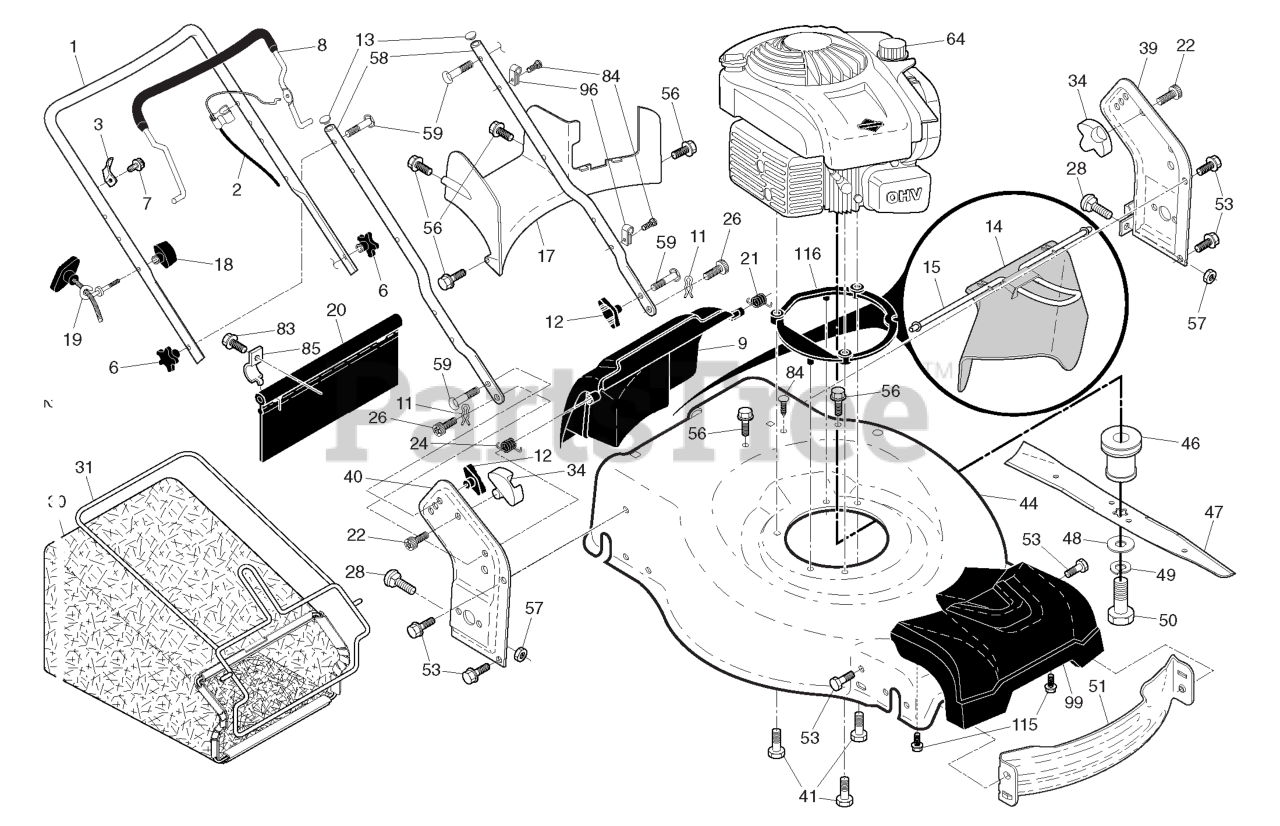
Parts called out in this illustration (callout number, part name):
1	HANDLE.UP.DST.SS/VS.FG/RG.NHGY
2	RP.CABLE.MZR.RGD.PLUS.STRT
3	BRACKET.UPSTOP.RT
6	KNOB.HANDLE.PLASTIC.STAR.BLACK
8	BAIL.ARM.ASSY:STRAIGHT OM
9	DOOR.REAR.ASM.22+GEN.FG/RG.498
11	COTTER.HAIRPIN.DOOR/HANDLE.PIV
12	KNOB, DEFLECTOR
13	PLUG.PLASTIC.7/8".14-20.GAUGE
14	DEFLECTOR.CHUTE.22+REAR
15	HANDLE DEFLECTOR.22+REAR
17	BAFFLE.REAR.22+RGD.AWD.PLASTIC
18	T-KNOB.NEW ROPE GUIDE
19	GUIDE.ROPE.BLK.ZINC.CHROM
20	SKIRT.REAR.22PLUS.RGD.LW(2 2MC
21	SPRING.LH.BLACK
22	SCREW.PAN.HEAD.#10
24	SPRING.RH.GRAY
26	SCREW,DOOR/HANDLE.PIVOT
28	BOLT.CARRIAGE.LN.5/16-18X.5/8
30	GBAG.AWD.HUSQ.A361029EM.GRY/SL
31	FRAME.GBAG.22+.BLK
34	BRACKET.GRASSBAG.ATTACHING.BLK
39	BRACKET.ASM.HANDLE.LT.22+.GREY
40	BRACKET.ASM.HANDLE.RT.22+.GREY
44	KIT.HSG.22+AWD.RR.WO.668.TRI
46	ADAPTER.BLADE.7/8.B&S.AWD
47	BLADE.22PLUS
48	WASHER,HARDEN
49	LOCKWASHER
50	BOLT.BLADE
51	BAFFLE.FRONT.22.PLUS
53	BOLT.5/16HEX.WHS.HD
56	SCREW.HX.13X.750
57	NUT.FLANGE.5/16
58	HANDLE.LOWER.22+.BT.GRAY
59	BOLT, HANDLE 5/16-18X1.75
83	TAPPING SCREW
84	FASTENER.PUSH.O.250X0.783
85	BRACKET.SKIRT.22+.BZP
96	CLIP.CABLE.BLK
99	COVER.ASSEMBLY.FRONT.22+AWD
115	SCREW.SHOULDER.5/16X1.375
116	SPACER.AWD.B&S
